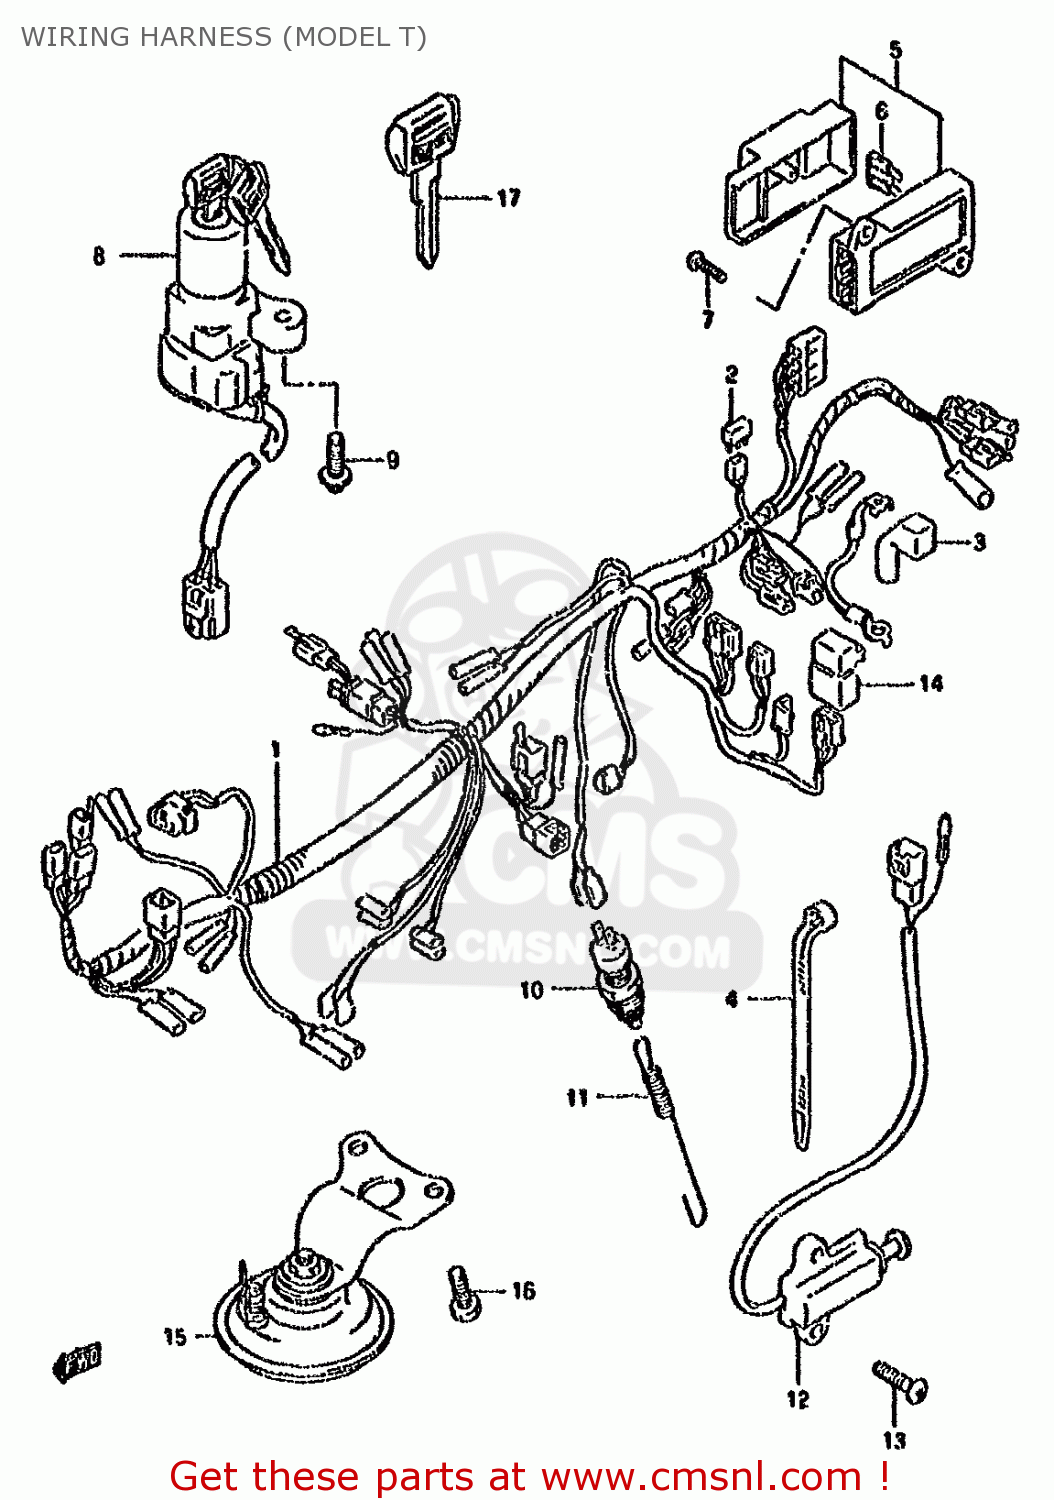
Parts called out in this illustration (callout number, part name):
1	HARNESS,WIRING
2	DIODE(STANLEY DE8804)
3	CAP,BATTERY PLUS TERMINAL
4	CLAMP(L:95)
5	BOX ASSY,FUSE
6	FUSE(10A)
7	SCREW
8	LOCK ASSEMBLY,STEERING
9	SCREW(6X18)
10	SWITCH ASSY,STOP LAMP
11	SPRING
12	LOCK ASSEMBLY,STEERING
13	BOLT
14	RELAY ASSY
15	SPRING
16	SWITCH ASSEMBLY,SIDE STAND
17	BOLT
18	RELAY ASSEMBLY
19	HORN ASSY
20	BOLT
21	WIRE, HORN RELAY
22	RELAY ASSY
23	BRACKET,TURN SIGNAL RELAY
24	BOLT
25	KEY,BLANK
